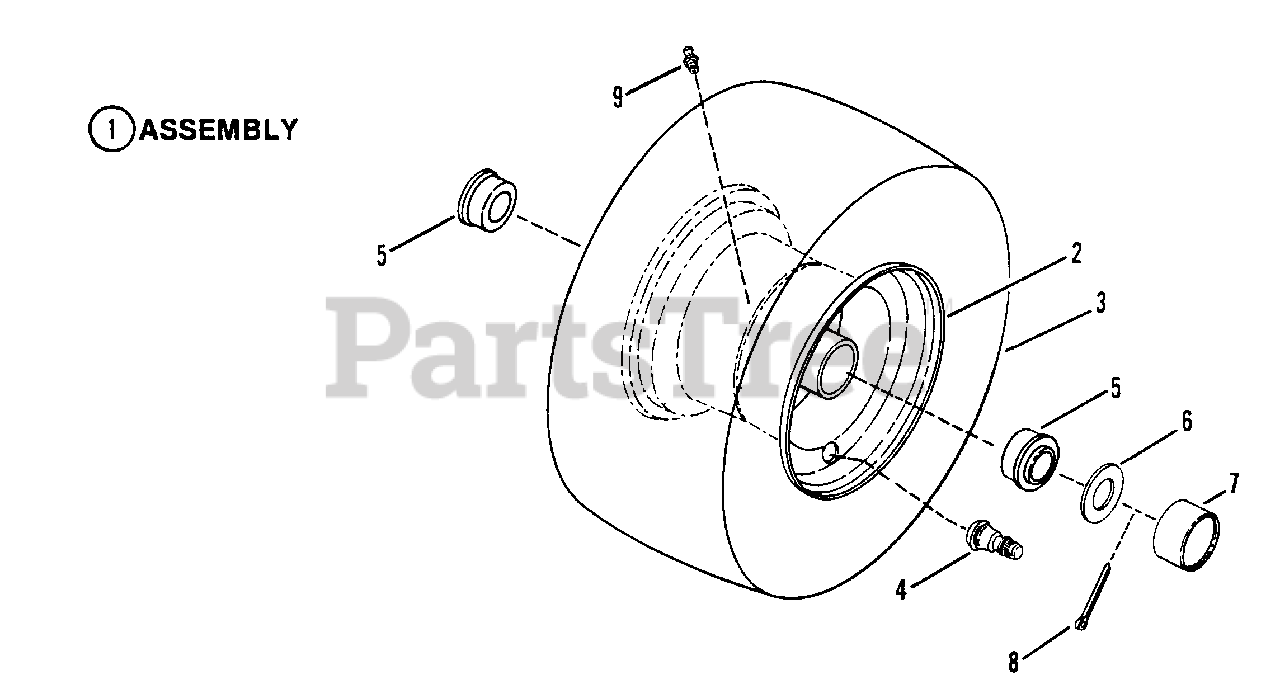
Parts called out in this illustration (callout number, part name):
1	ASSEMBLY, Front Tire & Rim
2	RIM
3	TIRE, 15 x 6.00 x 6
4	VALVE, Air
5	HEIM BEARING, Wheel
6	WASHER
7	COVER, Dust
8	COTTER-PIN
9	FITTING, Lube 1/4-28 Tapered Thread
